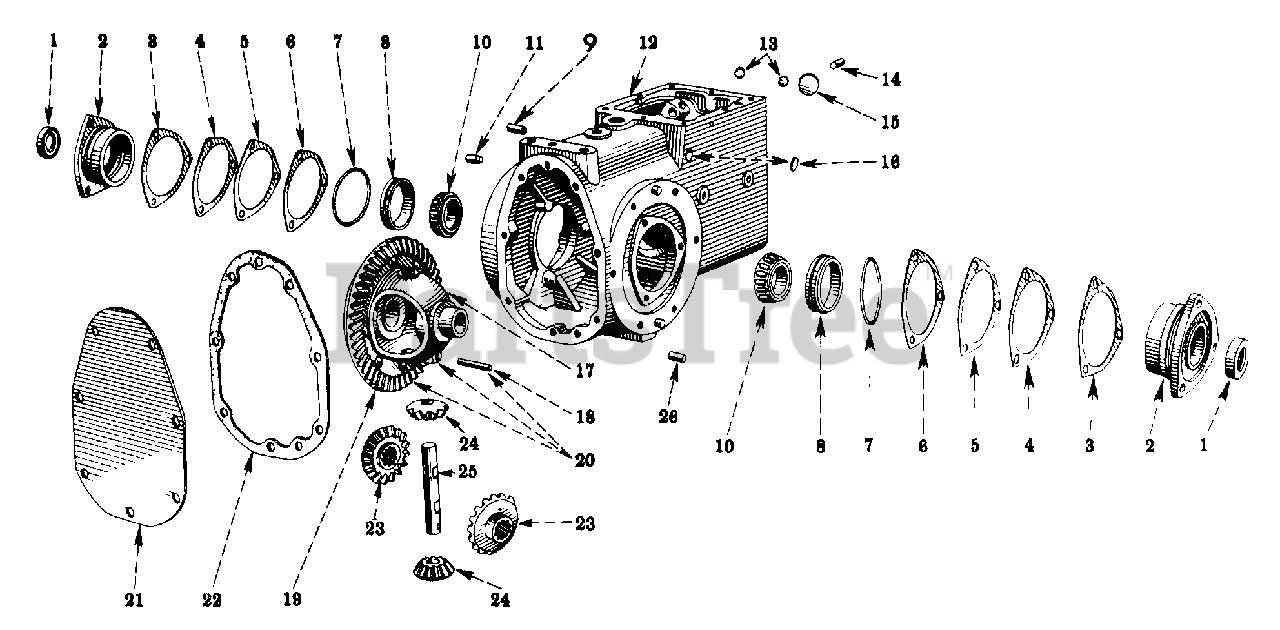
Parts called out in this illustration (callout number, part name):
1	OIL SEAL, DIFFERENTIAL SHAFT INNER BEARING RETAINER
2	RETAINER, DIFFERENTIAL
3	SHIM, DIFFERENTIAL BEARING RETAINER
4	SHIM, DIFFERENTIAL BEARING RETAINER
5	SHIM, DIFFERENTIAL BEARING RETAINER
6	SHIM, DIFFERENTIAL BEARING RETAINER
7	O-RING, 3-1/8 X 3-3/8 X 1/8 DIFFERENTIAL BEARING RETAINER
8	BEARING, DIFFERENTIAL SHAFT INNER CUP
9	BUSHING, ACTUATING TOGGLE
10	BEARING ASSY, DIFFERENTIAL CONE
11	DOWEL, TRANSMISSION CASE TO REAR AXLE HOUSING
12	CASE ASSY, TRANSMISSION
13	PLUG, 9/16 DIAMETER EXPANSION
14	DOWEL, TRANSMISSION CASE TO CLUTCH HOUSING
15	PLUG, 1-3/16 DIAMETER EXPANSION
16	PLUG, 11/16 DIAMETER EXPANSION
17	CASE, DIFFERENTIAL
18	PIN DIFFERENTIAL PINION SHAFT LOCK
19	GEAR, DIFFERENTIAL DRIVE - 46 TEETH
20	CASE ASSY, DIFFERENTIAL
21	PLATE, TRANSMISSION CASE REAR COVER
22	GASKET, TRANSMISSION CASE REAR COVER PLATE
23	GEAR, DIFFERENTIAL SIDE - 16 TEETH
24	PINION, DIFFERENTIAL - 10 TEETH
25	SHAFT, DIFFERENTIAL PINION
26	DOWEL, TRANSMISSION CASE TO DIFFERENTIAL SHAFT HOUSING
